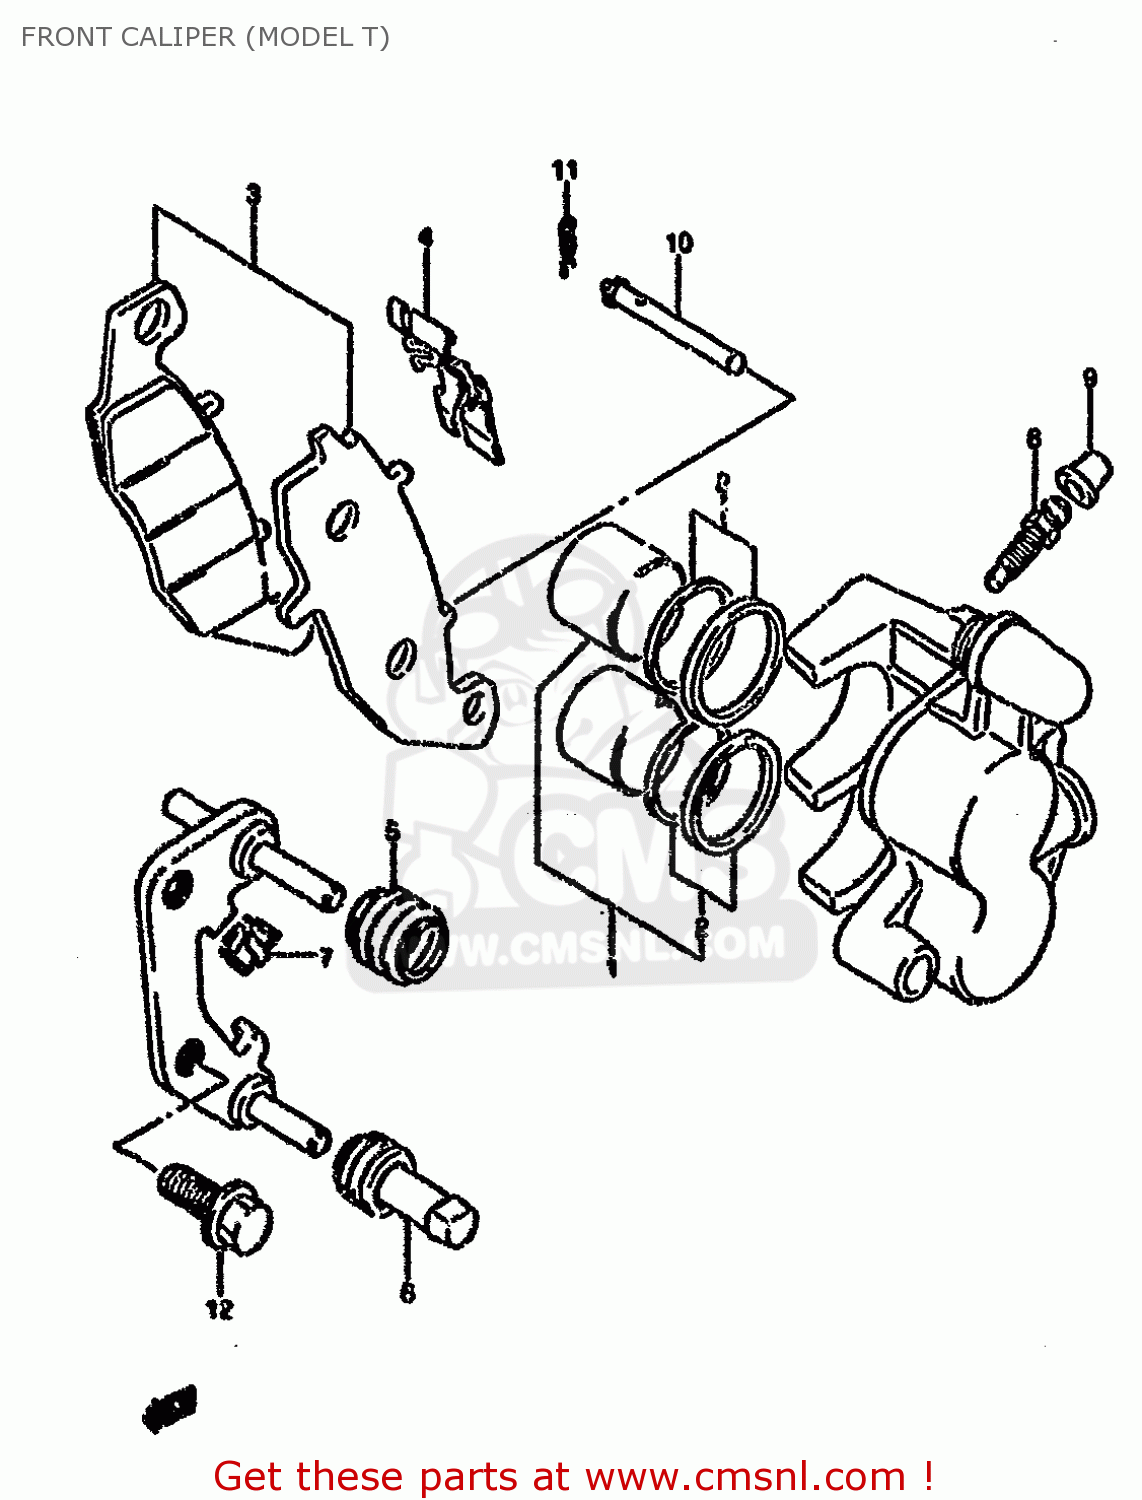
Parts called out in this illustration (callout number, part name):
1	PISTON SET
2	SEAL SET,PISTON
3	PAD SET (NAS)
4	SPRING,PAD,L
5	BOOT,AXLE
6	INSULATOR,AXLE
7	GUIDE,PAD
8	BLEEDER
9	CAP,BLEEDER PLUG
10	PIN,PAD
11	CLIP,PAD PIN
12	BOLT
13	CAP,BLEEDER PLUG
14	BOLT
